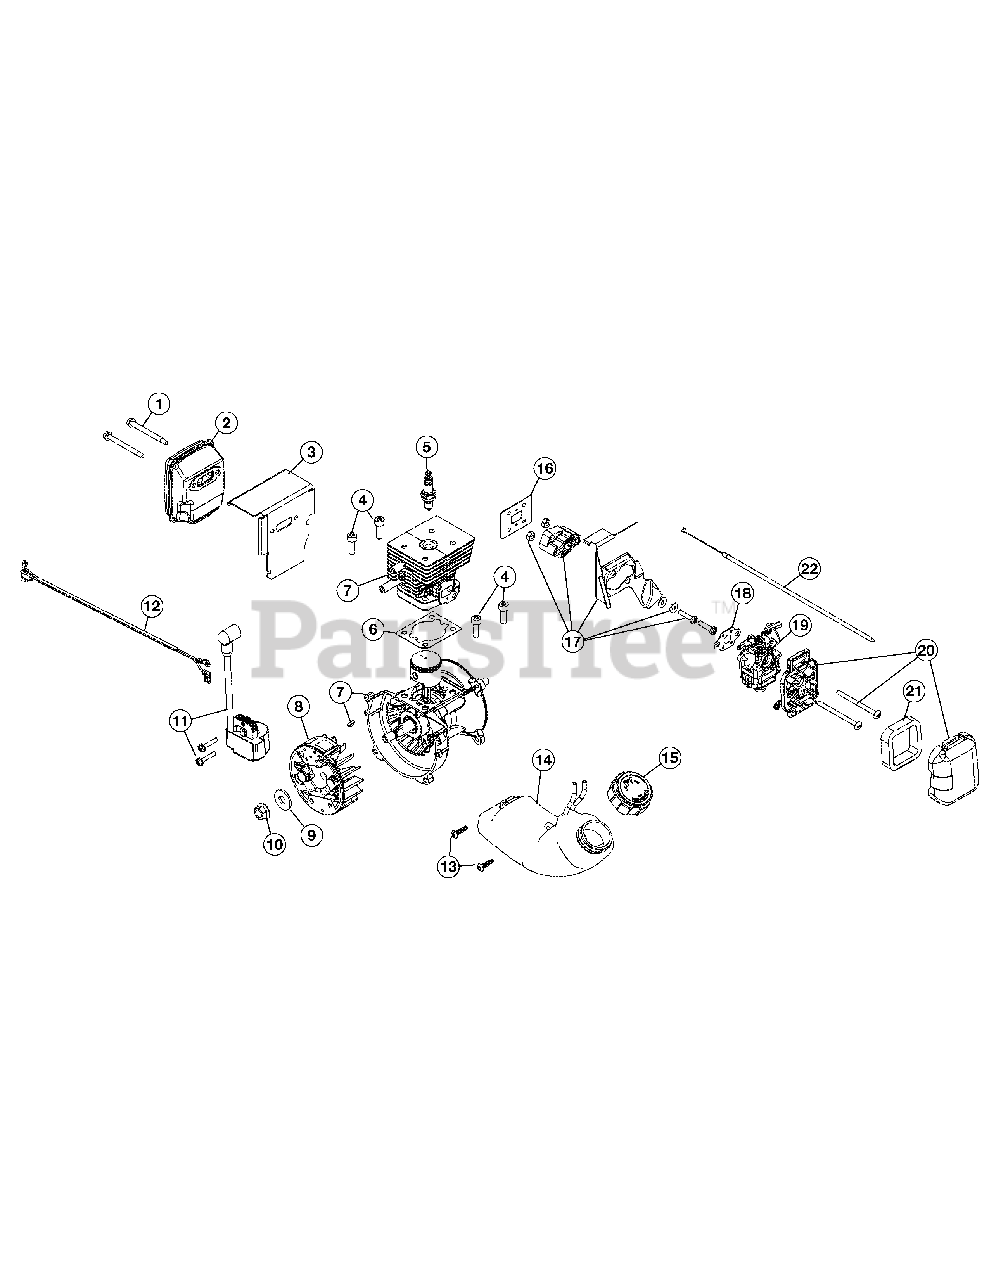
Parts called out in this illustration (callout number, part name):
1	Muffler Screws
2	Muffler Assembly
3	Muffler Gasket
5	Spark Plug
6	Cylinder Gasket
7	Shortblock Assembly
8	Flywheel Assembly
11	Module Assembly
14	Fuel Tank Assembly
16	Insulator Gasket
17	Insulator Assembly
18	Carburetor Gasket
19	Carburetor Assembly
20	Aircleaner Assembly
22	Throttle Cable
